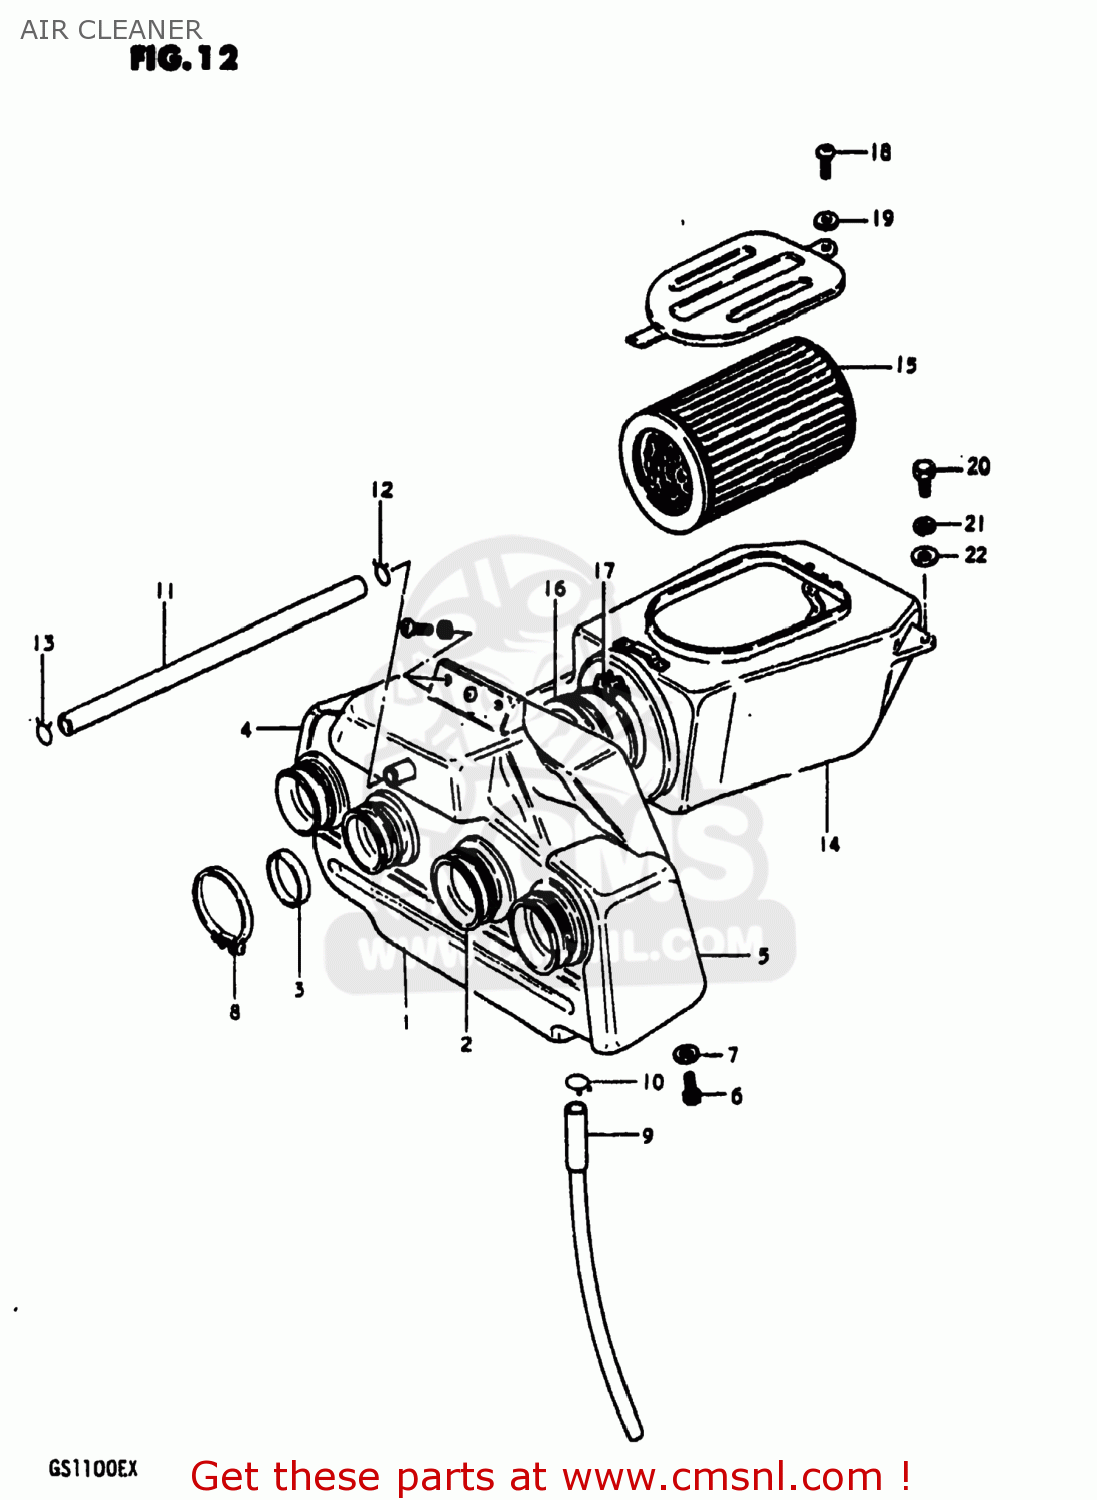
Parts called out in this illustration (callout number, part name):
1	CASE COMP,AIR CLEANER
2	TUBE,AIR CLEANER OUTLET
3	RING,CARBURETOR AIR IN
4	COVER,AIR CLEANER,RIGHT
5	COVER,AIR CLEANER,LEFT
6	SCREW
7	WASHER
8	CLAMP
9	DRAIN TUBE
10	CLIP
11	HOSE
12	CLIP,BREATHER HOSE
13	CLIP
14	CLEANER ASSEMBLY,AIR
15	FILTER,AIR CLEANER
16	JOINT,HOSE AIR CLEANER
17	CLAMP
18	SCREW
19	WASHER
20	BOLT, UPPER
21	LOCK WASHER
22	WASHER
